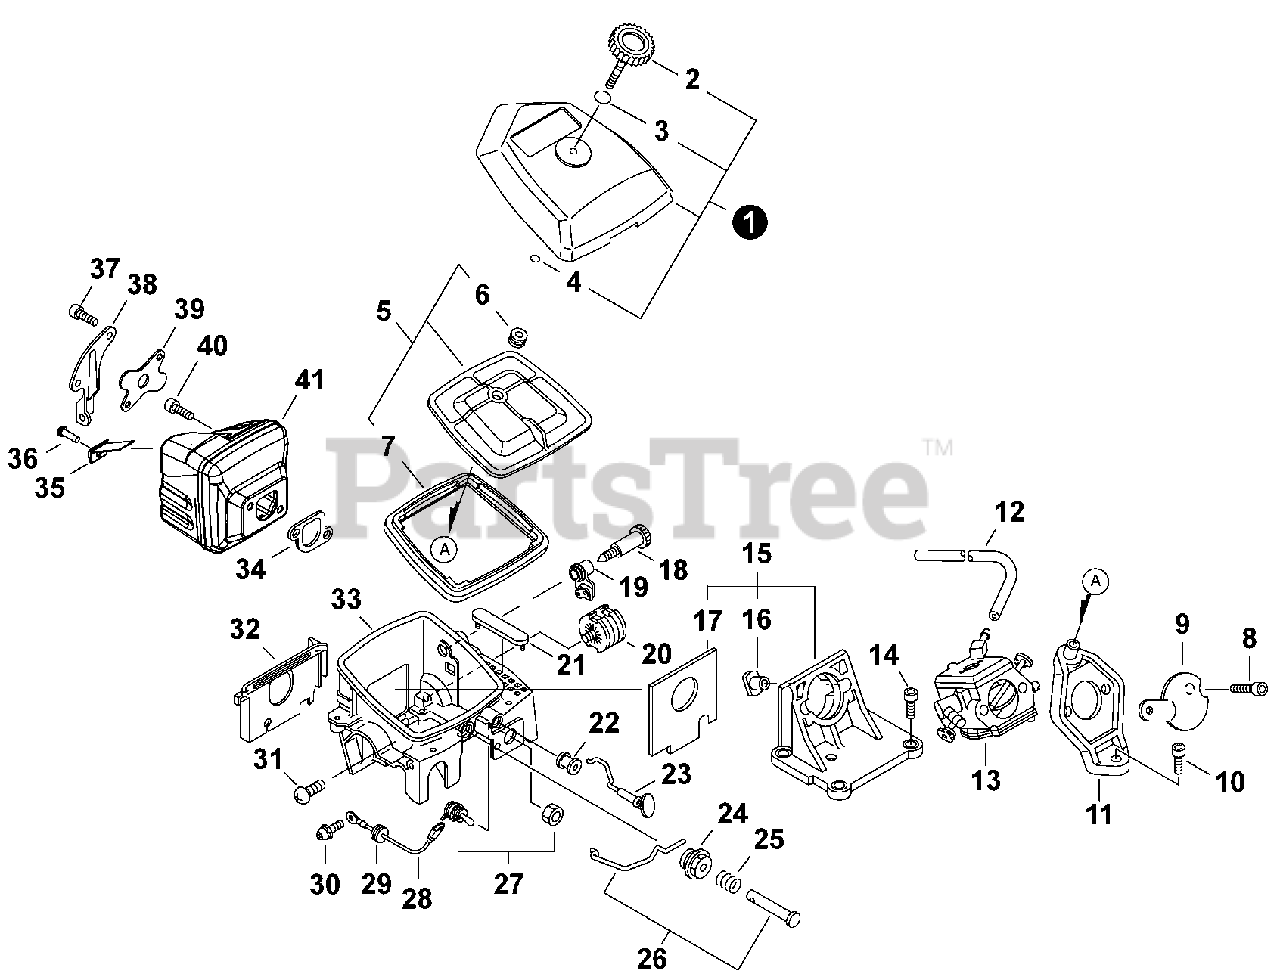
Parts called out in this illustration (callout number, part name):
1	COVER ASSY, AIR FILTER
2	THUMBSCREW
3	O-RING 10
4	O-RING 3
5	FILTER ASSY, AIR
7	SEAL, AIR FILTER
8	BOLT 5×55
10	BOLT 5×20
11	BRACKET, AIR FILTER
12	PIPE, IMPULSE 3×6(8)×160
13	CARBURETOR HDA-324
14	BOLT 5×25
15	INSULATOR KIT, INTAKE
17	SEAL, DUST
18	SCREW, IDLE ADJUST - ORANGE
19	GROMMET, NEEDLE
21	PLUG
22	GROMMET, CHOKE
23	ROD, CHOKE
24	GROMMET, THROTTLE ROD
26	THROTTLE ROD KIT
27	SWITCH, ON-OFF
30	SCREW 4×8
31	SCREW 4×8
32	PLATE, GUIDE
33	CASE, CARBURETOR - ORANGE
34	GASKET, MUFFLER
35	SCREEN, SPARK ARRESTER
36	SCREW 4×8
37	BOLT 5×10
38	BRACKET, MUFFLER
39	COVER, MUFFLER
40	BOLT 6×20
41	MUFFLER
